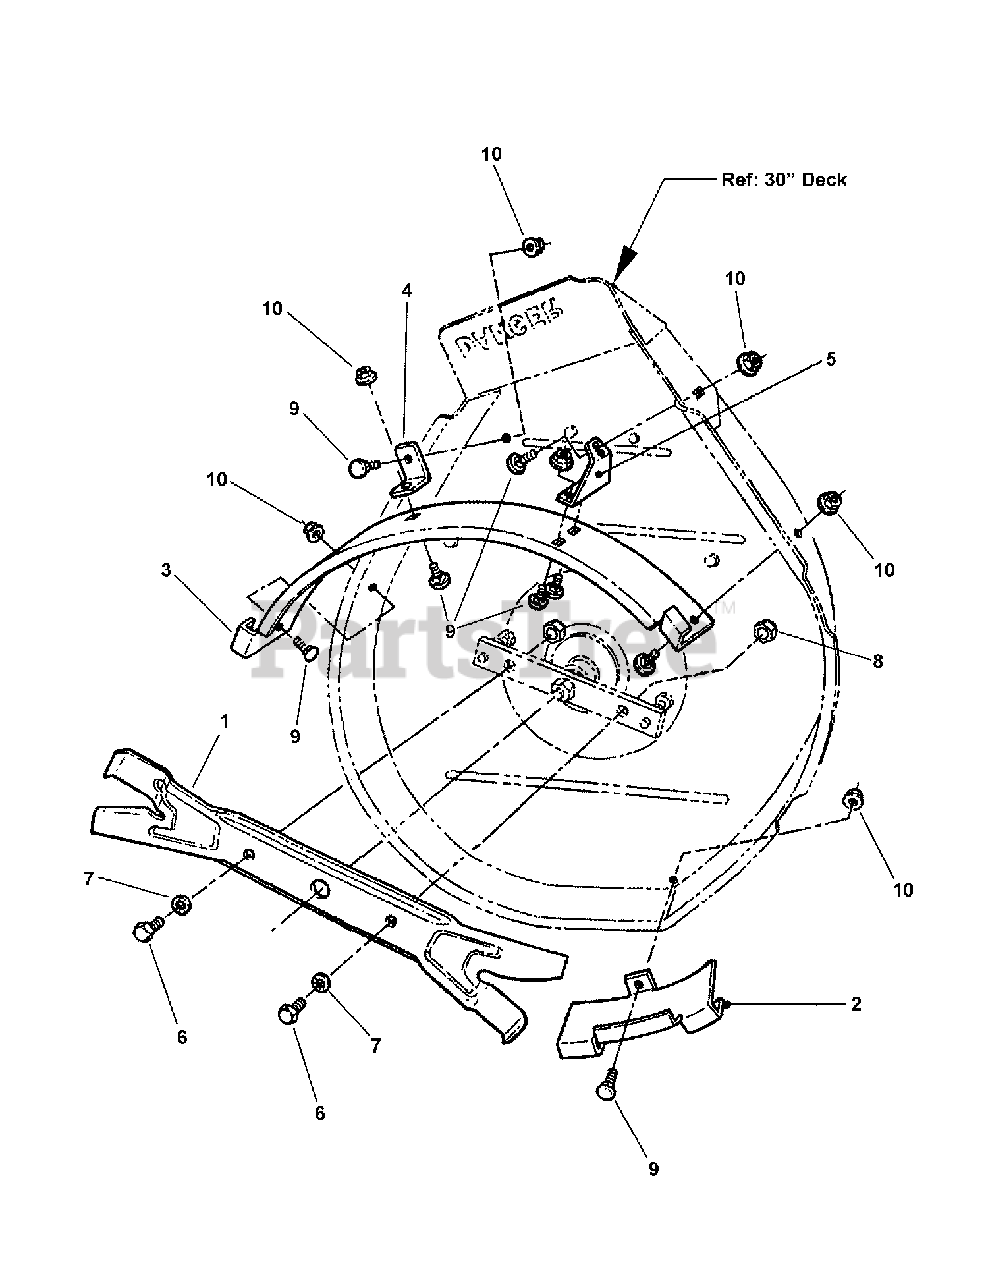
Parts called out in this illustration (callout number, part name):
1	BLADE, Ninja, 30"
2	BAFFLE, 30" Deck (small)
3	BAFFLE, 30" Deck (large)
4	ANGLE, Brace, 30" Deck
5	ANGLE, Brace, 30" Deck
6	SCREW, 1/2-20 x 1-1/4" Hex Head Cap, GR 5
7	WASHER, 1/2" Internal Tooth Lock
8	NUT, 1/2-20 Hex, GR 5
9	BOLT, 5/16-18 x 5/8" Short Square Neck Carriage, GR 5 BZ
10	NUT, 5/16-18 Hex Flange Lock, GR 5
